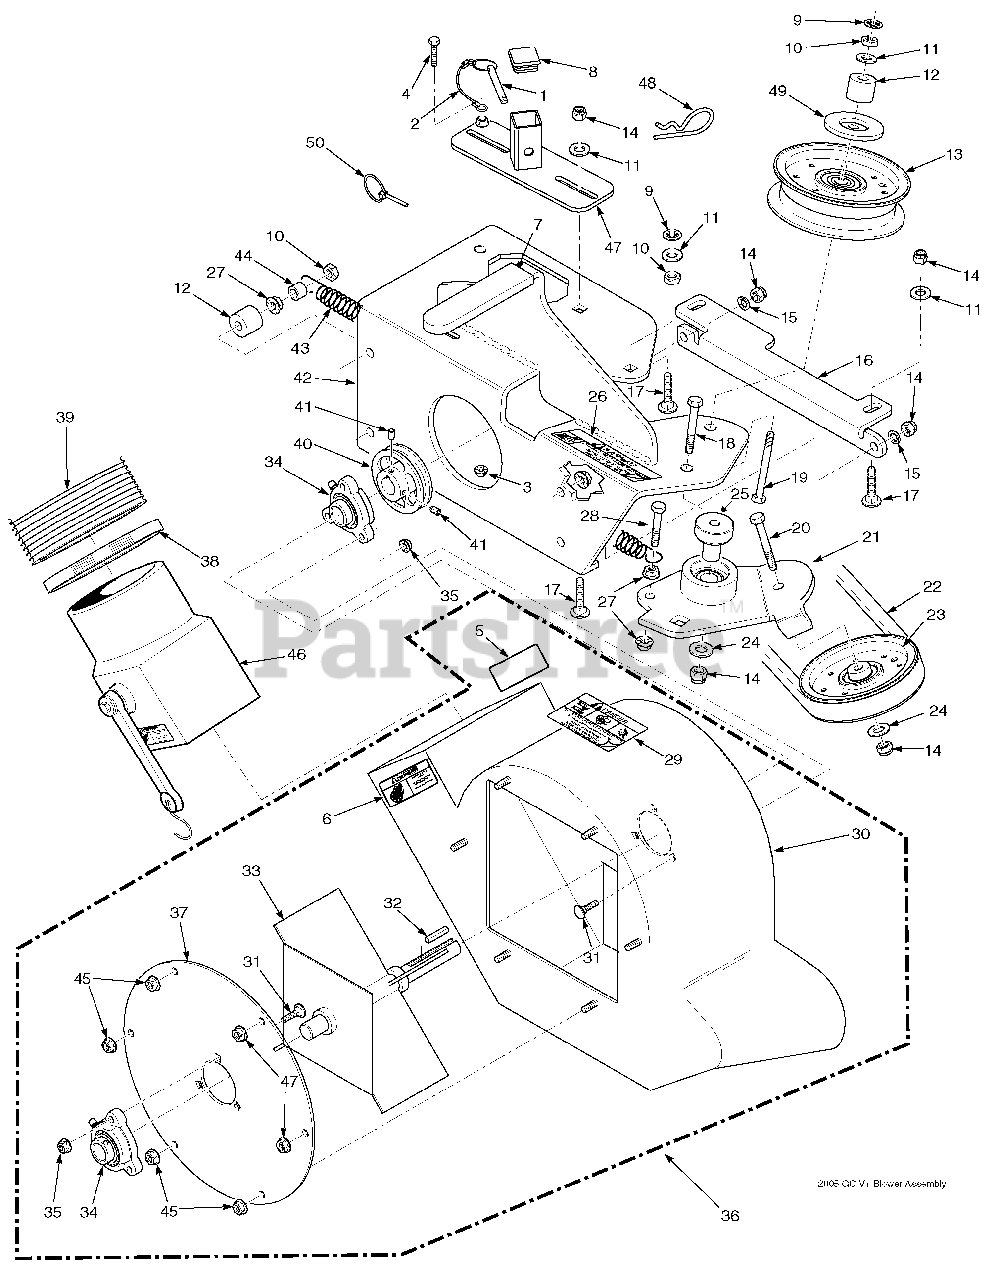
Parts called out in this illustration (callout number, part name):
1	Pin, Ring 2-1/4" Long
2	Lanyard, Deck Height Pin
3	Nut, Serr. Flange 1/4-20
4	Bolt, Hex Head 1/4-20 x 1-1/4"
5	Decal, Blower
6	Decal, Rotating Blower
7	Grip, Blower Lever
8	Cap, Square
9	Nut, Push On 3/8 Thread
10	Lock Nut, 3/8-16
11	Flatwasher, 3/8-.391 x .938 x .105
12	Spacer
13	Pulley, Idler 4" Dia. - 61"
14	Nut, Elastic Stop 3/8-16
15	Lockwasher, 3/8-16
16	Plate, Catcher Mounting
17	Bolt, Carr. 3/8-16 x 1-1/2"
18	Bolt, Hex Head 3/8-16 x 3" - 52"
19	Bolt, Hex Head 3/8-16 x 3-1/2"
20	Bolt, Hex Head 3/8-16 x 1-3/4"
21	Idler Arm Assembly - 61"
22	Belt, GC-STT-61V
23	Pulley, 3-1/2" O.D., GC-STC
24	Washer, 3/8 Hardened
25	Pivot, Idler - 61"
26	Decal, Belt Cover
27	Nut, Serr. Flange 3/8-16
28	Bolt, Hex Head 3/8-16 x 1-1/2 Gr. 8
29	Decal, Danger
30	Blower Housing Weldment w/Decals
31	Bolt, Carr. 5/16-18 x 3/4" Gr. 5
32	Key, 1/4 x 1/4 x 1-1/2"
33	Fan Weldment
34	Bearing Assembly
35	Nut, Elastic Stop 5/16-18
36	Blower Housing Assembly, GC-STT
37	Cover, Blower Housing
38	Clamp, 8-5/8" Max Dia.
39	Hose, 8" Dia. x 68" Long
40	Pulley, 4-3/4" O.D. - 1" Bore
41	Set Screw, 5/16-18 x 3/8"
42	Frame, Blower Mount
43	Spring, Main Drive
44	Spacer
45	Nut, Serr. Flange 5/16-18
46	Adapter w/Strap
47	Receiver Weldment, Mount Post - 61"
48	Hair Pin Cotter, .177 x 3-1/4"
49	Dust Shield
50	Quick Pin, 5/16" Dia.
